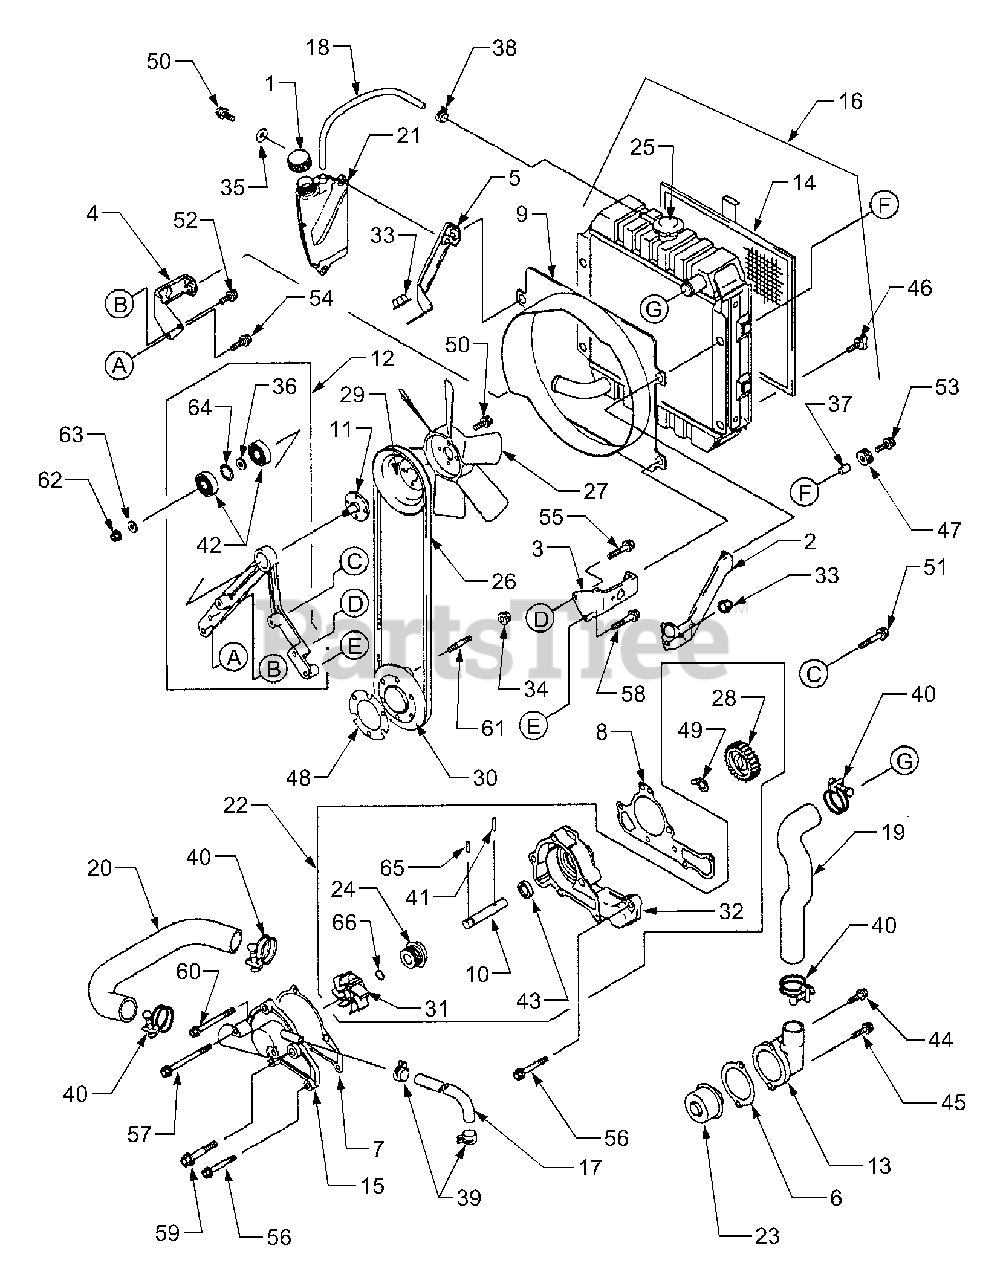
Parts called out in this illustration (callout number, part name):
1	Cap, Reservoir
6	Gasket, Thermostat Cover
7	Gasket, Pump Cover
8	Gasket, Pump Case
10	Shaft, Impeller
11	Shaft, Pulley
12	Housing Assembly
13	Cover, Thermostat
15	Cover, Pump
16	Radiator Assembly
17	Hose, Cooling, 7.5 x 13.5 x 30.5
18	Hose, Cooling, 7.5 x 10.5 x 46
19	Hose, Cooling
20	Hose, Cooling
22	Pump, Water
24	Seal, Mechanical
25	Cap Assembly, Pressure
36	Spacer, 12 x 18 x 1.4
42	Bearing, Ball
44	Bolt, .6 x 40
45	Bolt, .6 x 20
48	Shim, 0.6 Thk
50	Bolt, Flanged, 6 x 16
51	Bolt, Flanged, 6 x 35
52	Bolt, Flanged, 8 x 20
53	Bolt, Flanged, 8 x 25
54	Bolt, Flanged, 8 x 30
55	Bolt, Flanged, 8x 40
56	Bolt, Flanged, 6 x 45
57	Bolt, Flanged, 6 x 75
58	Bolt, Flanged, 8 x 45
59	Bolt, Flanged, 8 x 70
60	Bolt, Flanged, 6 x 65
62	Nut, Hex Fine
63	Washer, Plain
